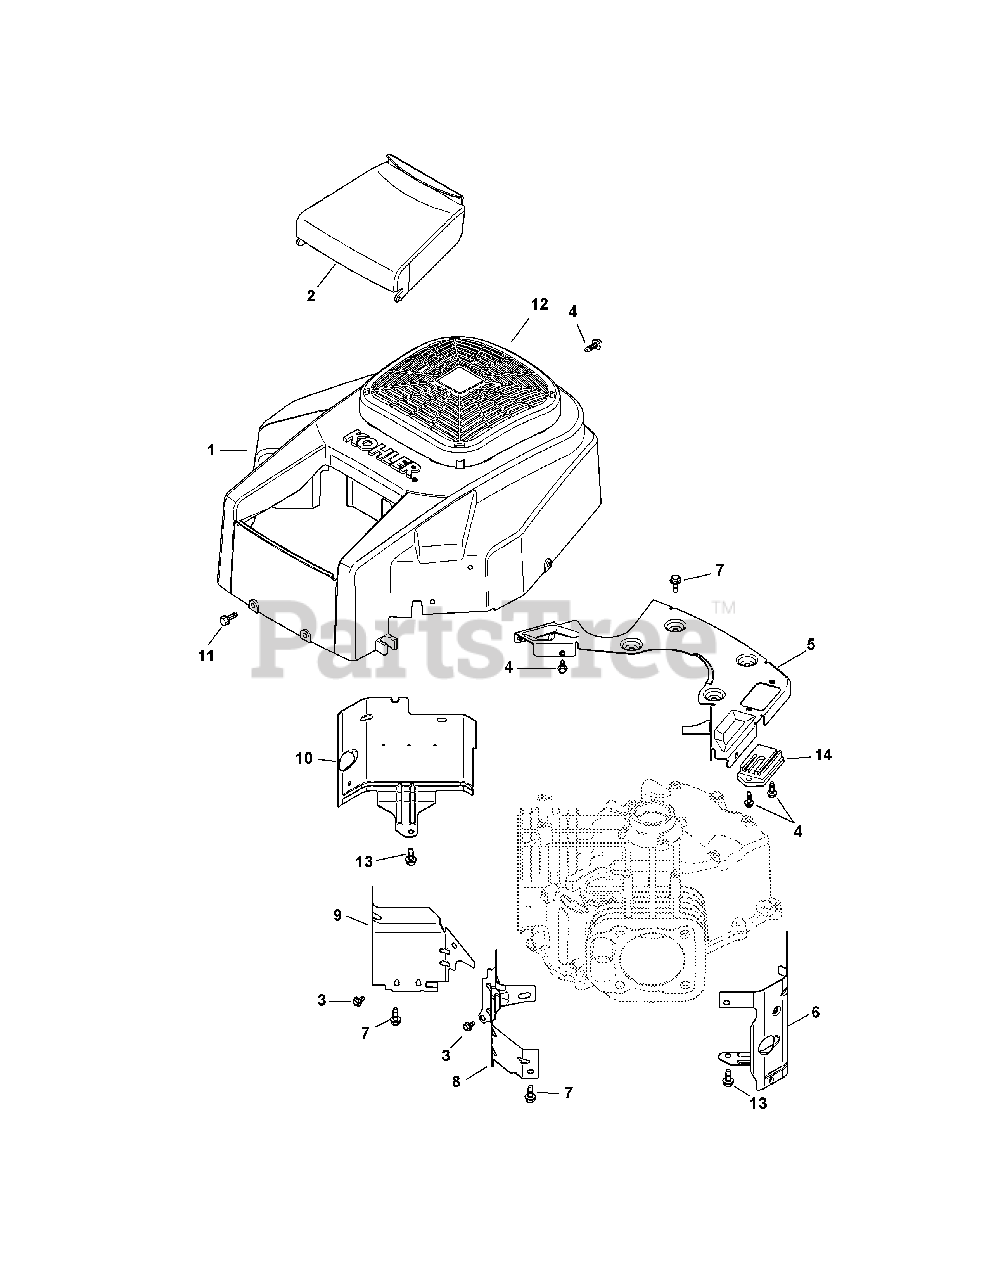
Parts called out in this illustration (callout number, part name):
1	Blower Housing Kit
2	Air Cleaner Cover
3	Flange Screw, M5 x .8 x 10
4	Flange Screw, M5 x .8 x 16
5	Backing Plate Kit
6	Cylinder Barrel Baffle, #2 Side
7	Flange Screw, M6 x 1.0 x 16
8	Valley Baffle, #2 Cylinder
9	Valley Baffle, #1 Cylinder
10	Cylinder Barrel Baffle, #1 Side
11	Screw, M6 x 1.7 x 18
13	Flange Screw, M6 x 1.0 x 10
14	Regulator/Rectifier
